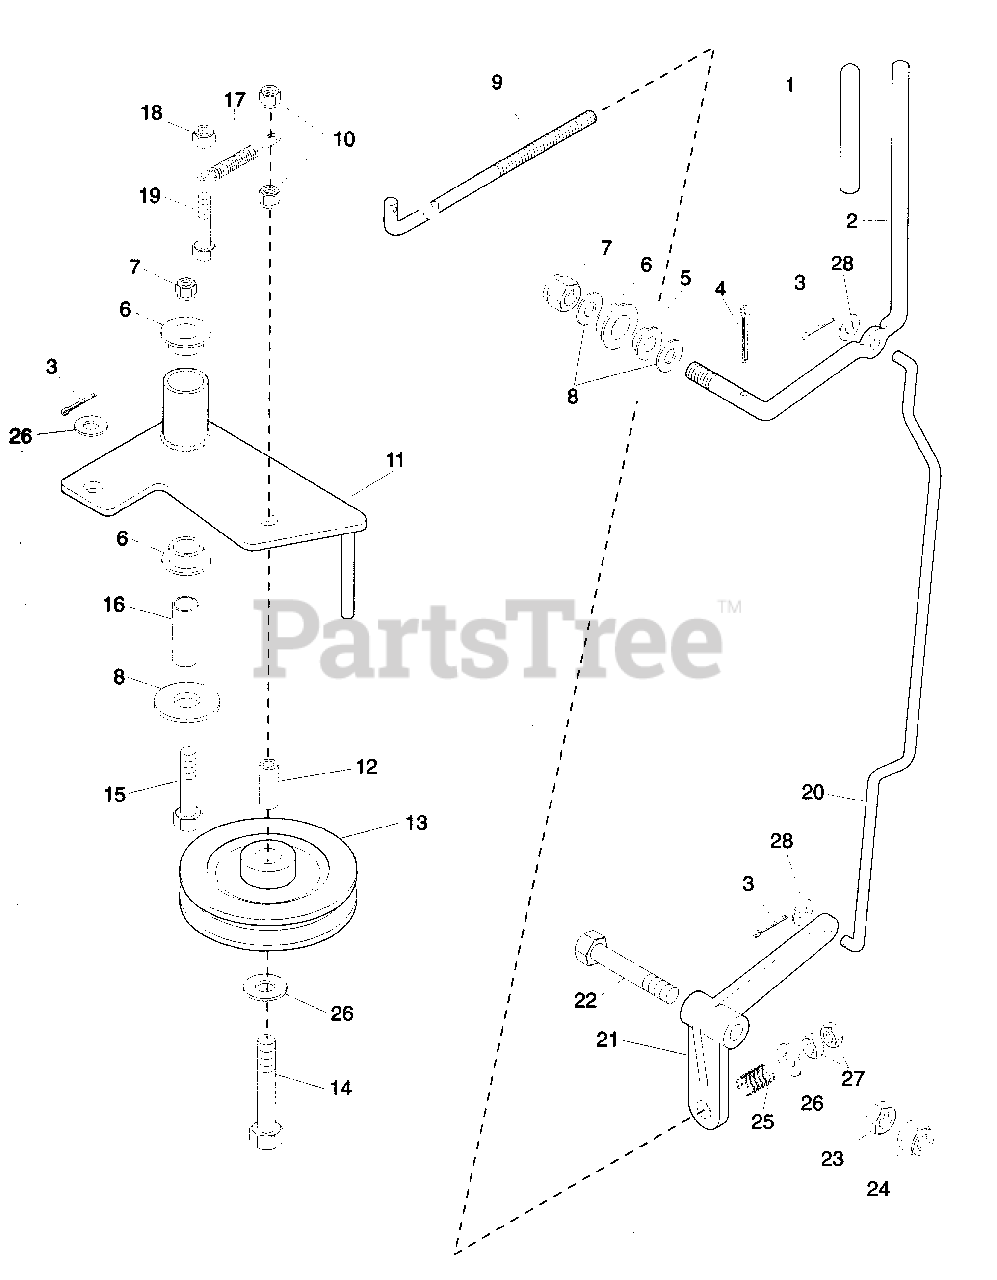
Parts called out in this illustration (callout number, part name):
1	Grip, PTO Lever
2	Lever, PTO Actuating
3	Pin-Cotter .09 x 1.00
4	Pin-Cotter .188 x 1.50
5	Bushing-Flange .515 x .750 x .745 x 1.00
6	Bushing-Flange .762 x 1.0 x .580 x 1.48
7	Nut-Locking-Center .50-13
8	Washer-Flat-Steel .50 x 1.25 x .083
9	Assembly, Tire/Wheel, Pro-100
10	Nut-Locking-Center .38-16
11	Declutch Arm-Pro PTO
12	Spacer .391 ID x .75 OD x 1.25
13	Idler-Pulley-Flat 3.25 x .625
14	Bolt-Hex .38-16 x 3.50 Grade 5
15	Bolt-Hex .50-13 x 3.25 Grade 5
16	Bushing for Declutch Arm Pivot
17	Spring-Tension .095 x .85 x 4.38
18	Nut-Locking-Center .31-18
19	Bolt-Hex .31-18 X 1.25 Grade 5
20	PTO Lever Link Rod, Pro 100
21	Lever, PTO Clutch
22	Bolt-Hex .50-13 x 2.50 Grade 5
23	Nut-Hex .50-13
24	Nut-Locking-Center .50-13
25	Spring-Compression .125 x .78 x 1.00
26	Washer-Flat-Steel .406 x .812 x .065
27	Nut-Hex .38-16
28	Washer-Flat-Steel .344 x .688 x .065
